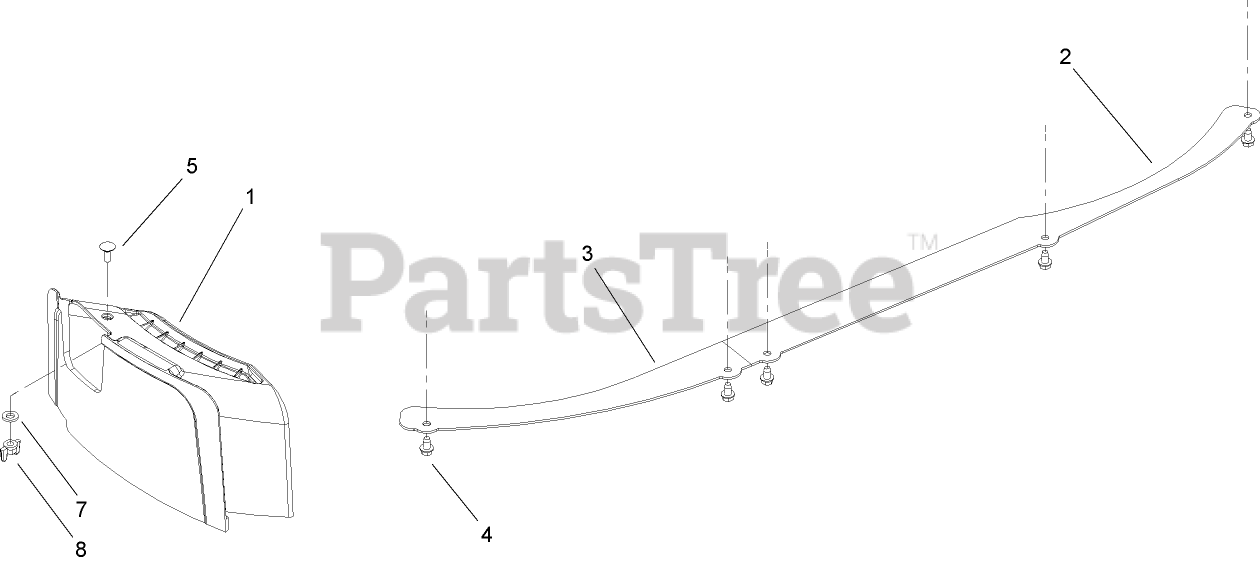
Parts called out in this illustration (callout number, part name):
1	PLUG-MULCHING
2	SKIRT-DECK, LH
3	SKIRT-DECK, RH
4	SCREW-TAP
5	BOLT-CARR
7	WASHER-BELL
8	NUT-WING, PLASTIC
